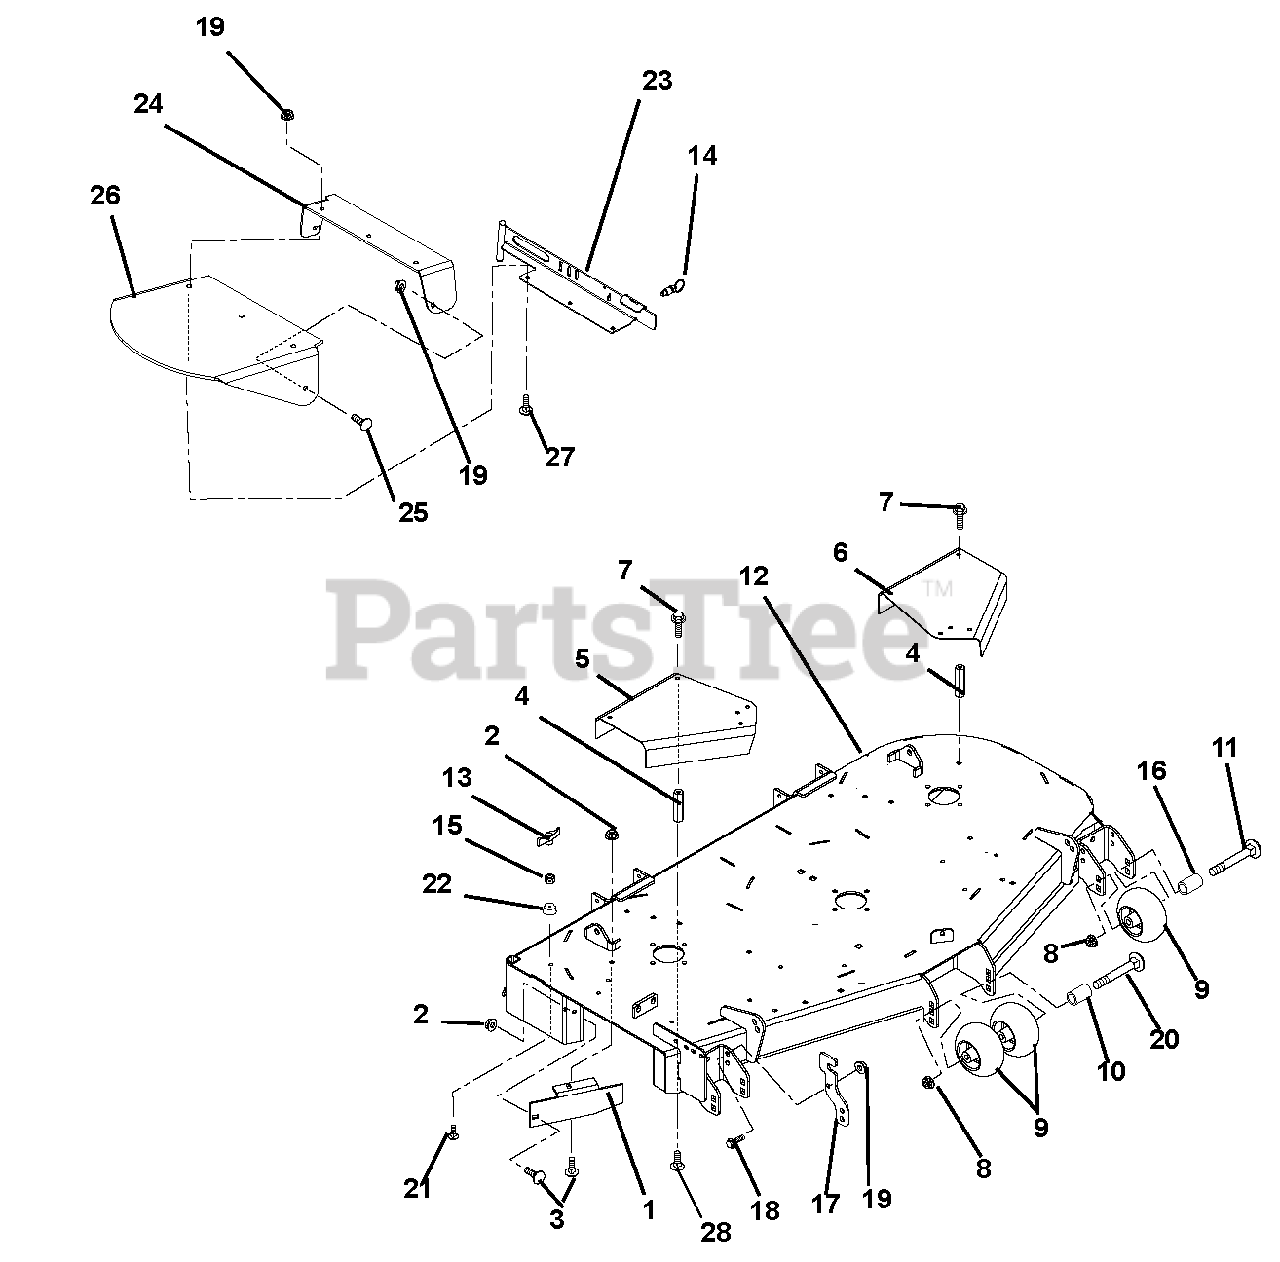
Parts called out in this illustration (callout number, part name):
1	52-in. Discharge Baffle (992146, 148, 149, 150)
2	Nut, .31-18 Nyloc Flange
3	Bolt, Round Head Square Neck .31-18 x 1.00 Grade 5
4	Nut, Coupling .31-18 x 3.00
5	52-in. Right Hand Spindle Guard (992146, 148, 149, 150)
6	52-in. Left Hand Spindle Guard (992146, 148, 149, 150)
7	Bolt, SEMS .31-18 x .62
8	Nut .50-13 Nyloc Flange
9	Anti-Scalp Wheel
11	Bolt-Round Head Square Neck .50-13X5.00
12	52-in. Mower Deck (992146, 148, 149, 150)
13	Knob, Wing .312-18
14	Pin, Plunger Pull .50-13 Thread x .310 Diameter
15	Nut, Locking, Center .31-18
16	Spacer, .510 x .625 x 3.35
17	Chute, Storage Bracket
18	Bolt, Hex .38-16 x 1.00
19	Nut, .38-16 Nyloc Flange
20	Bolt, Round Head Square Neck .50-13 x 8.50
21	Bolt, Round Head Square Neck .31-18 x 1.50
22	Bumper, Recessed 1.50 x .63 , .31 Thru Hole
23	52-inch and 60-inch Discharge Chute Mounting Weldment (992146, 147, 148, 149, 150, 151, 152, 153, 154, 155, 159)
24	Rubber Discharge Chute Support
25	Bolt, Round Head Square Neck .38-16 x 1.00 Grade 5
26	Chute, Rubber Discharge
27	Bolt, Round Head Square Neck .38-16 x 1.25 Grade 5
28	Bolt, Round Head Square Neck .31-18 x .75
